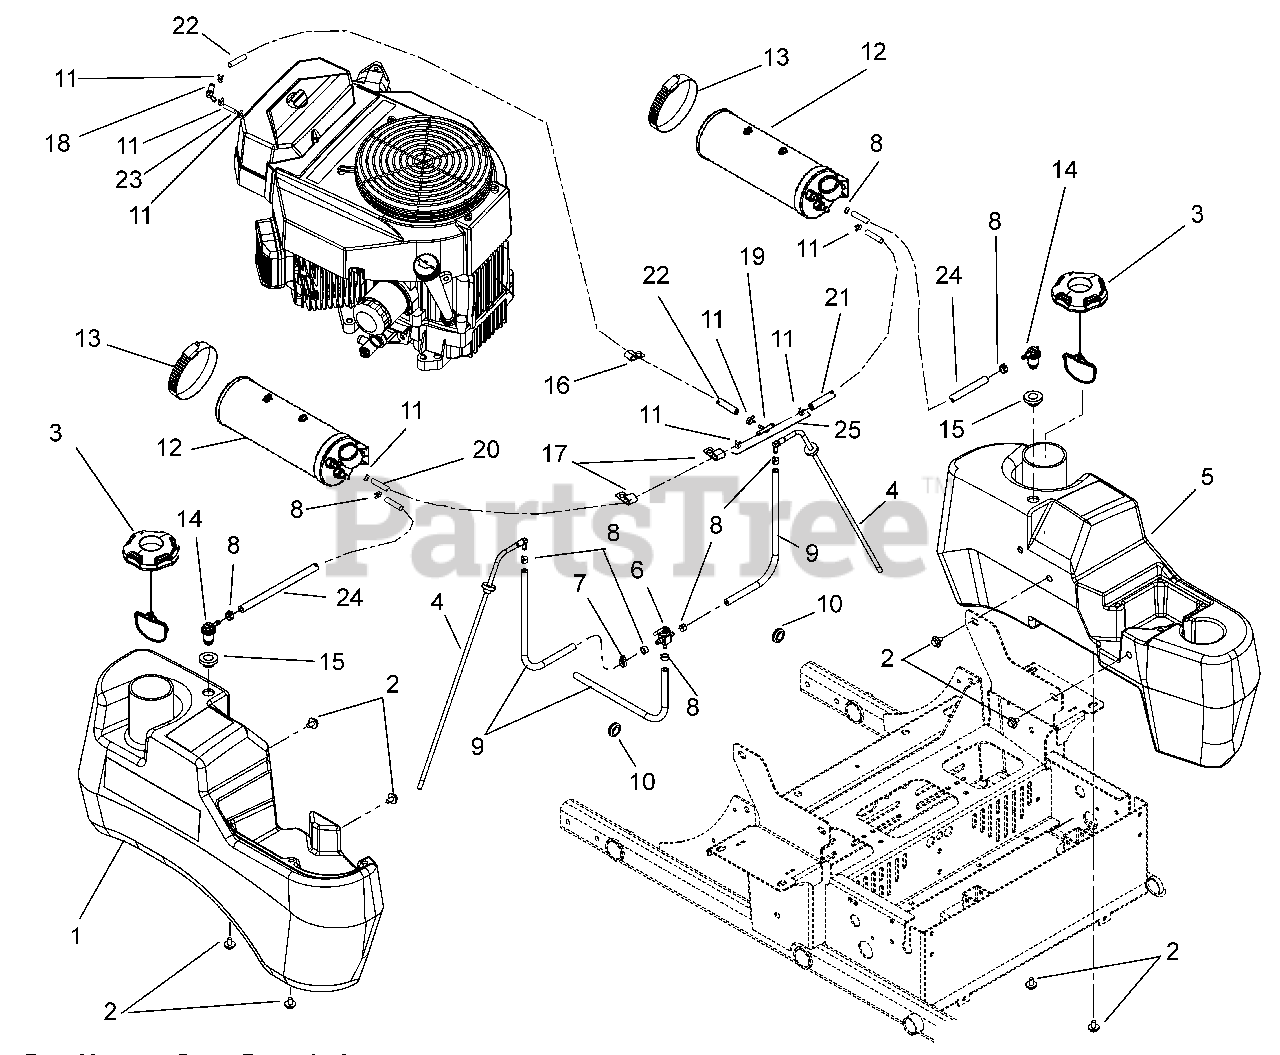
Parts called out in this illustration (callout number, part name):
1	Tank, Right Hand Fuel
2	Bolt, SEMS .31-18 x .62
3	Cap, Fuel, Non-Vented Autolock
4	Assembly, Large Tank Fuel Pick-Up
5	Tank, Left Hand Fuel
6	Valve, Fuel
7	Routing Clip (1/2" ID)
8	Clamp, Fuel Line .25
9	Hose, .25 Low-Perm Bulk Gas
10	Grommet, Rubber 5/8 ID/1.13 OD
11	Clamp, Hose, Spring .188
12	Canister, Carbon 9.36 Cap
13	Clamp, Worm Hose 2.3/3/2 SS #44
14	Valve, Combination
15	Grommet, Remote Vent Nitrile
17	Routing Clip, .50 ID
18	Hose, Elbow 90° .188
19	Assembly, Vapor Line
20	Hose, .188 Low-Perm Bulk Gas
21	Hose, .188 Low-Perm Bulk Gas
22	Hose, .188 Low-Perm Bulk Gas
23	Hose, .188 Low-Perm Bulk Gas
24	Hose, .25 Low-Perm Bulk Gas
25	Vapor Line Assembly (CARB) (Includes items 11,18, 20, 21, 22, 23)
